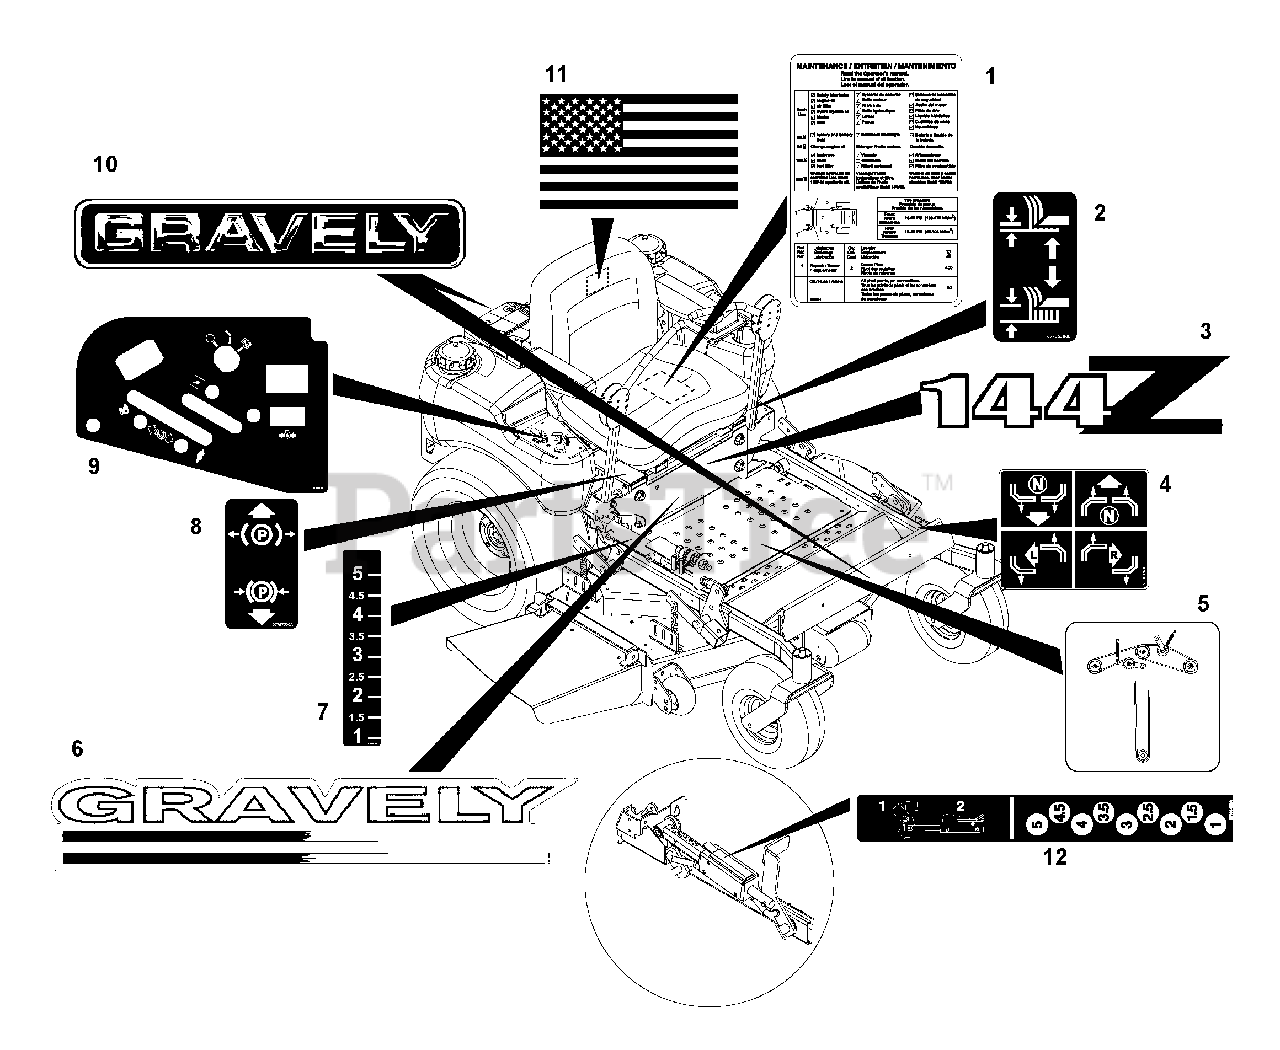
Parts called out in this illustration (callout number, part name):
1	Decal, Service Instructions
2	Decal, Lift Lever (992042, 043, 044, 051, 054, 055, 077, 078, 079, 080, 081, 082, 310, 311)
3	Decal, PM 152Z (992044, 054, 079, 081, 094, 096)
3	Decal, PM 144Z (992042, 064, 077, 083, 092, 310)
3	Decal, PM 148Z (992043, 078, 093, 311)
3	Decal, PM 160Z (992055, 080, 082, 095, 097)
4	Decal, Instructional Steering
5	Decal, Belt Diagram
6	Decal, ZT Hood
7	Decal, Height of Cut (992042, 043, 044, 051, 054, 055, 077, 078, 079, 080, 081, 082, 310, 311)
8	Decal, Parking Brake Lever
9	Decal, Control Panel
10	Decal, 15" Gravely Logo
11	Decal, American Flag
12	Decal, Height of Cut (992064, 083, 092, 093, 094, 095, 096, 097)
